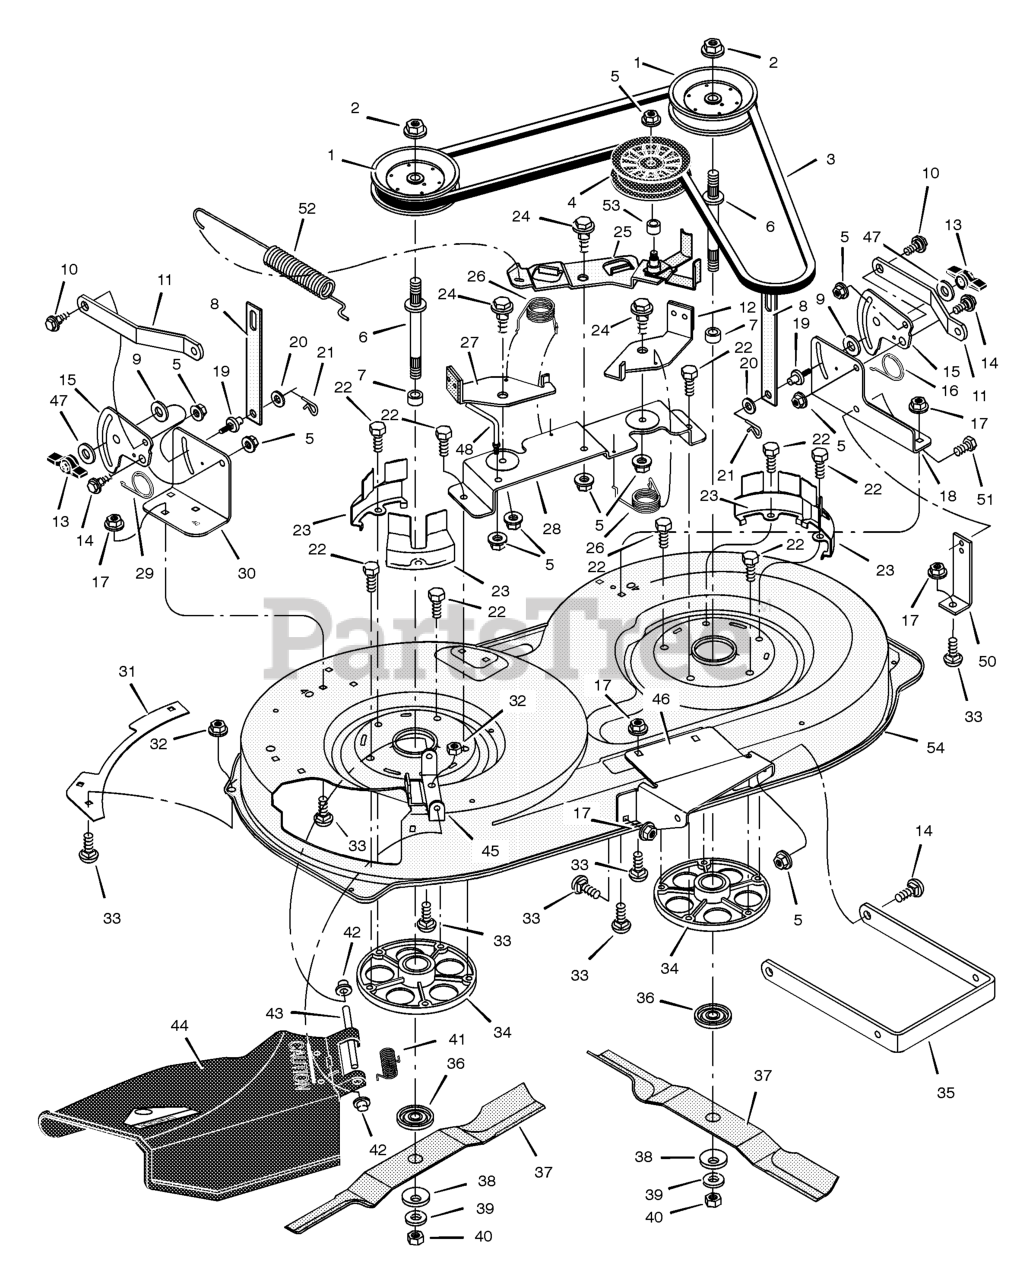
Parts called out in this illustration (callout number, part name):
1	Pulley, Jackshaft
2	Nut, Hex
3	Belt, Mower Drive
4	Pulley, Idler
5	Nut, Flange
6	Jackshaft
8	Link, Lift
9	Pad, Friction
10	Bolt, Shoulder
11	Bracket, Suspension
12	Pad Assembly, Left Brake
13	Knob
14	Bolt, Shoulder
15	Plate, Suspension
17	Nut, Flange
18	Bracket, Suspension
19	Pin, Hanger
21	Pin, Cotter
22	Bolt
23	Cover, Pulley
24	Bolt, Shoulder
25	Arm, Idler
27	Pad Assembly, Right Brake
28	Bracket Assembly, Brake
30	Bracket, Suspension
31	Plate
32	Nut, Flange
33	Bolt, Carriage
34	Mandrell
35	Bracket, Suspension
36	Adapter, Blade
42	Cap, Push On
43	ROD, Deflector
44	Deflector Assembly
45	Bracket, Deflector
46	Bracket, Front Hanger
48	Guide, Belt
50	Bracket, Support
52	Spring, Extension
54	Housing, Blade
55	Nut, Hex
